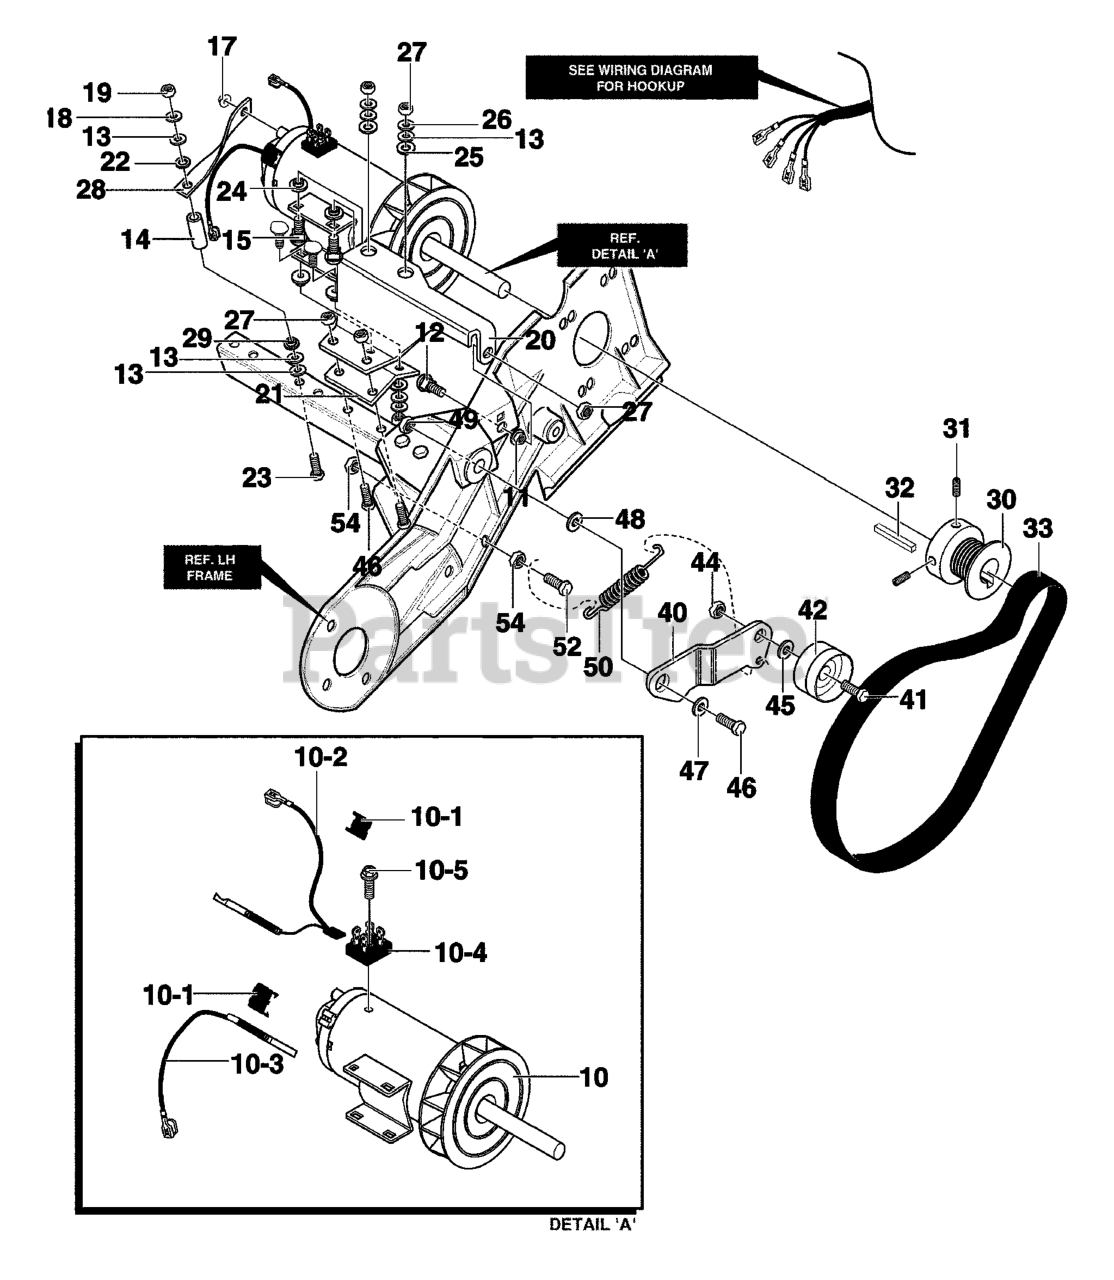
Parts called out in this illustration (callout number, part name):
10	MOTOR, ELECTRIC
10-1	BRUSH CAP
10-2	BRUSH CUT-OUT ASSY.
10-3	BRUSH ASSY.
10-4	RECTIFIER
10-5	SCREW, 10-24
11	NUT RETAINER
12	BOLT, 5/16-18 x .75
13	PLASTIC WASHER
14	TUBE, INSULATOR
15	BOLT, 5/16-18 x 1.00
17	NUT,#10-24
18	FLATWASHER
19	NUT, 1/4-20
20	BRACKET, UPPER MOTOR MT.
21	BRACKET, LOWER MOTOR MT.
22	FLATWASHER
23	SCREW, 1/4-20 x 1.00
24	INSULATOR, MOTOR
25	INSULATOR WASHER
26	FLATWASHER
27	NUT, 5/16-18
28	BRACE, MOTOR
29	SHOULDER WASHER
30	PULLEY, MOTOR
31	SCREW, 1/4-20 x .38
32	SQUARE KEY
40	IDLER BRACKET
41	SCREW, 3/8-16 x 1.50
42	IDLER PULLEY
44	NUT, 3/8-16
45	FLATWASHER
46	SCREW, 5/16-18 x 0.75
47	FLATWASHER
48	SPACER, SLEEVE
49	NUT, 5/16-18
50	IDLER SPRING
52	SCREW, 1/4-20 x 1.25
54	NUT. 1/4-20
